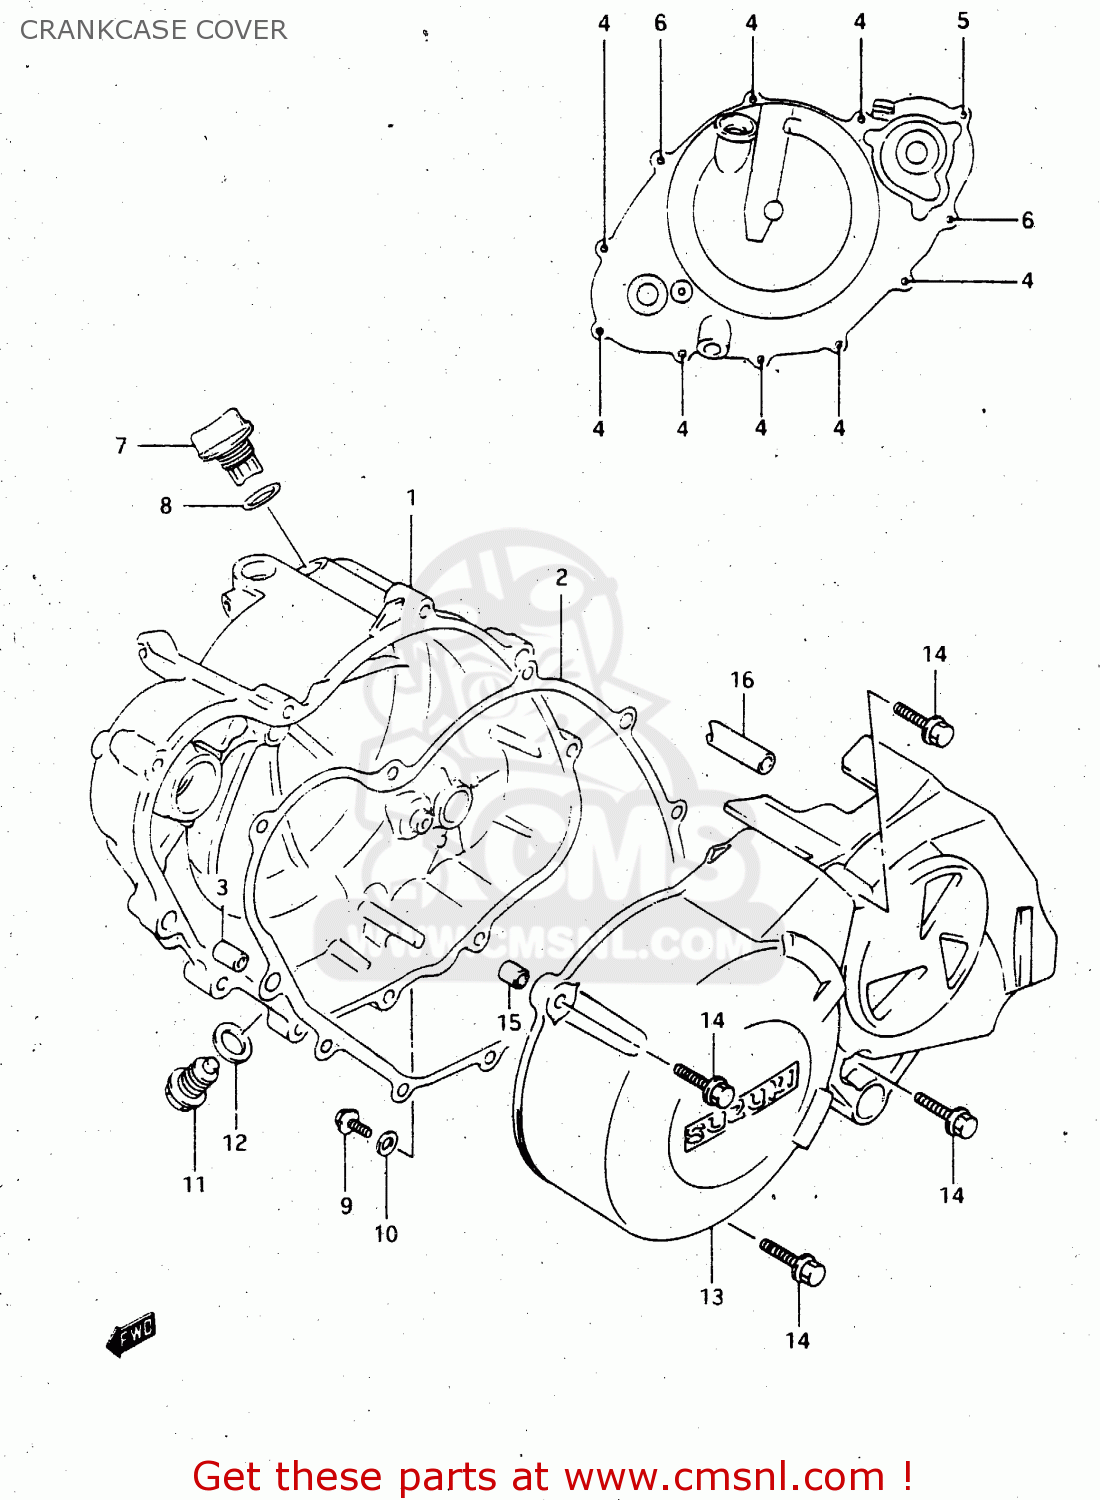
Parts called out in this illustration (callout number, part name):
1	COVER,CLUTCH
2	GASKET,CLUTCH COVER (NAS)
3	PIN
4	BOLT
5	BOLT
6	BOLT
7	PLUG,OIL FILLER
8	O RING(D:3.1,ID:16.8)
9	SCREW (6X10)
10	GASKET(6.2X11X1).2 (NAS)
11	PLUG
12	GASKET(13.8X18.8X4.8) (NAS)
13	COVER,MAGNETO
14	BOLT,UNDER
15	PIN
16	CUSHION,MAGNETO COVER
